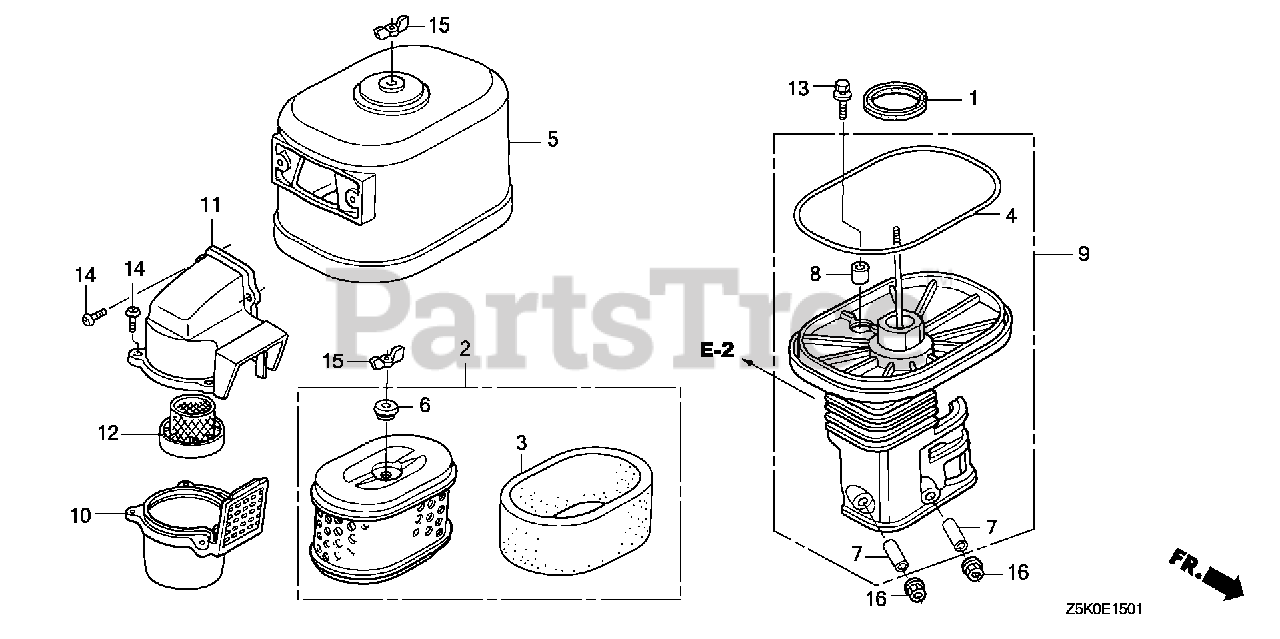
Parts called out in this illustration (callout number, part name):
1	GASKET, ELBOW
2	ELEMENT, AIR CLEANER
3	FILTER (OUTER)
4	SEAL, AIR CLEANER COVER
5	COVER, AIR CLEANER (CYCLONE)
6	GROMMET, AIR CLEANER
7	COLLAR, AIR CLEANER
8	COLLAR B, AIR CLEANER
9	ELBOW, AIR CLEANER
10	CASE, PRE AIR CLEANER
11	CAP, PRE AIR CLEANER
12	GUIDE, PRE AIR CLEANER
13	BOLT-WASHER (6X22)
14	SCREW, PAN (5X16.5)
15	NUT, TOOL BOX SETTING
16	NUT, FLANGE (6MM)
